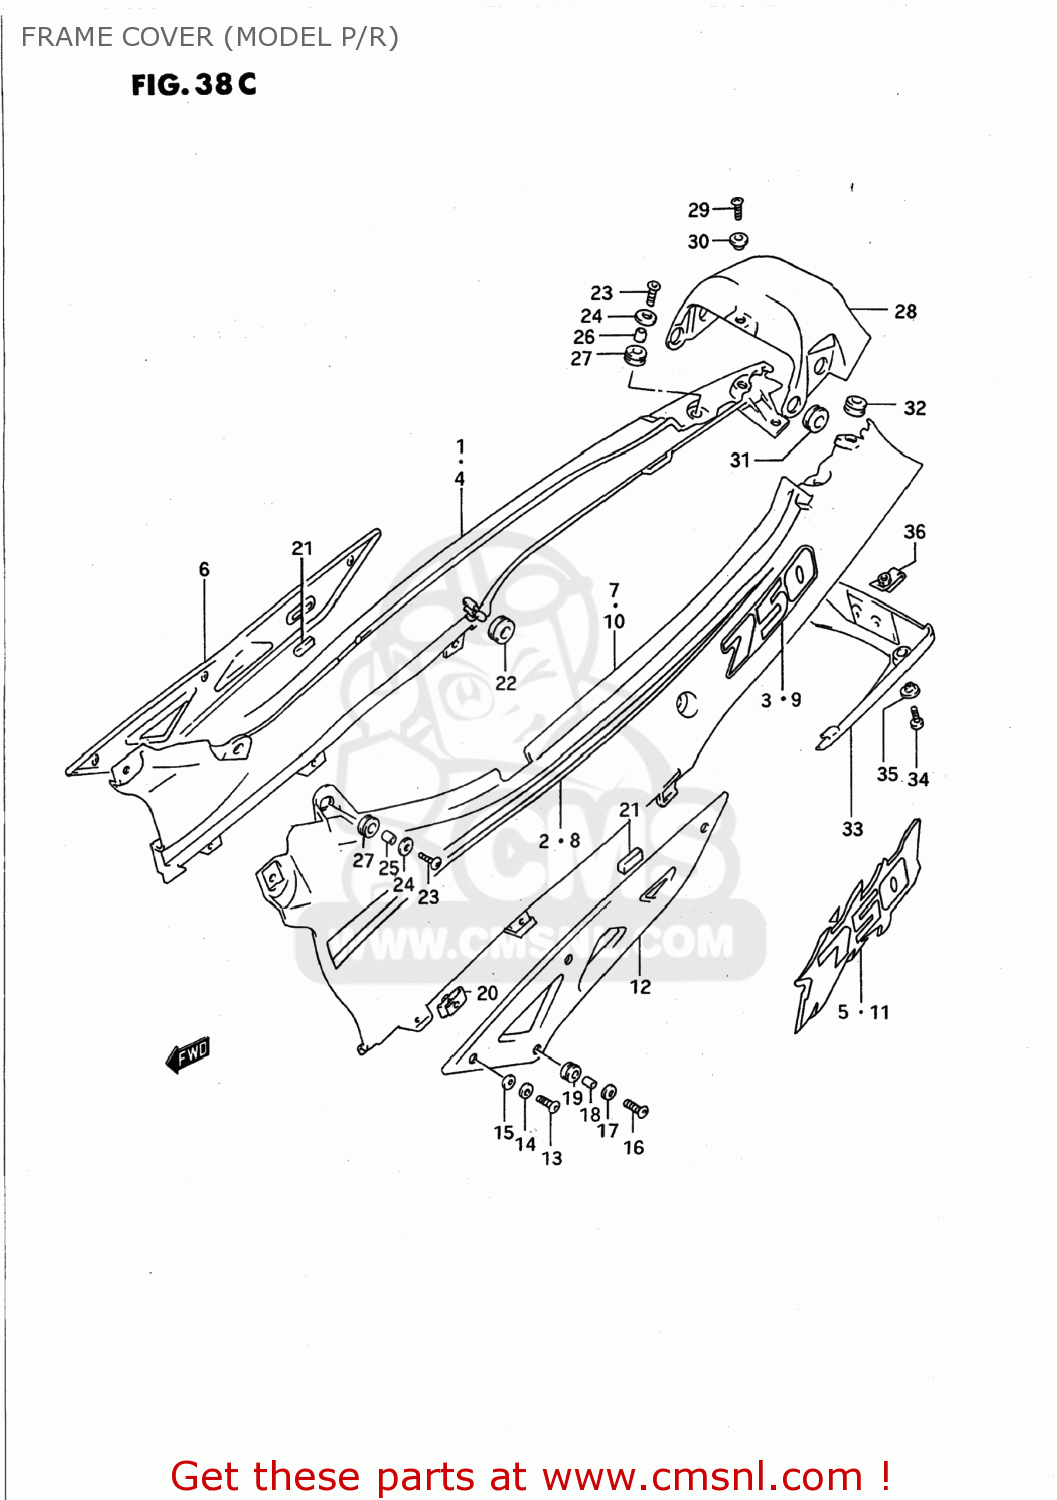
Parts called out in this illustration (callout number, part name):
1	COVER COMP,FRAME,RIGHT
2	TAPE,FRAME COVER STRIPE
3	EMBLEM,FRAME COVER
4	COVER,FRAME,R(BLACK)
5	EMBLEM,FRAME COVER
6	COVER,FRAME LWR,R
7	COVER,FRAME,L(BLACK)
8	TAPE,FRAME COVER STRIPE
9	EMBLEM,FRAME COVER
10	COVER COMP,FRAME,LEFT
11	EMBLEM,FRAME COVER
12	COVER,FRAME LWR,L
13	SCREW(6X16)
14	WASHER (6.7X16X1.8)
15	WASHER (5.5X16X1)
16	SCREW(6X16)
17	WASHER(6.5X22X1.6)
18	SPACER(6.2X8.3X6.1)
19	CUSHION
20	PLATE,FRAME COVER
21	CUSHION,FRAME COVER LWR
22	CUSHION
23	SCREW(6X16)
24	WASHER
25	SPACER(6.1X9X7.5)
26	SPACER (6.1X9X9)
27	CUSHION
28	COVER,FRAME CTR
29	SCREW 6X10
30	WASHER
31	GROMMET
32	CUSHION
33	COVER,FRAME RR
34	SCREW
35	WASHER
36	PLATE,FRAME COVER
